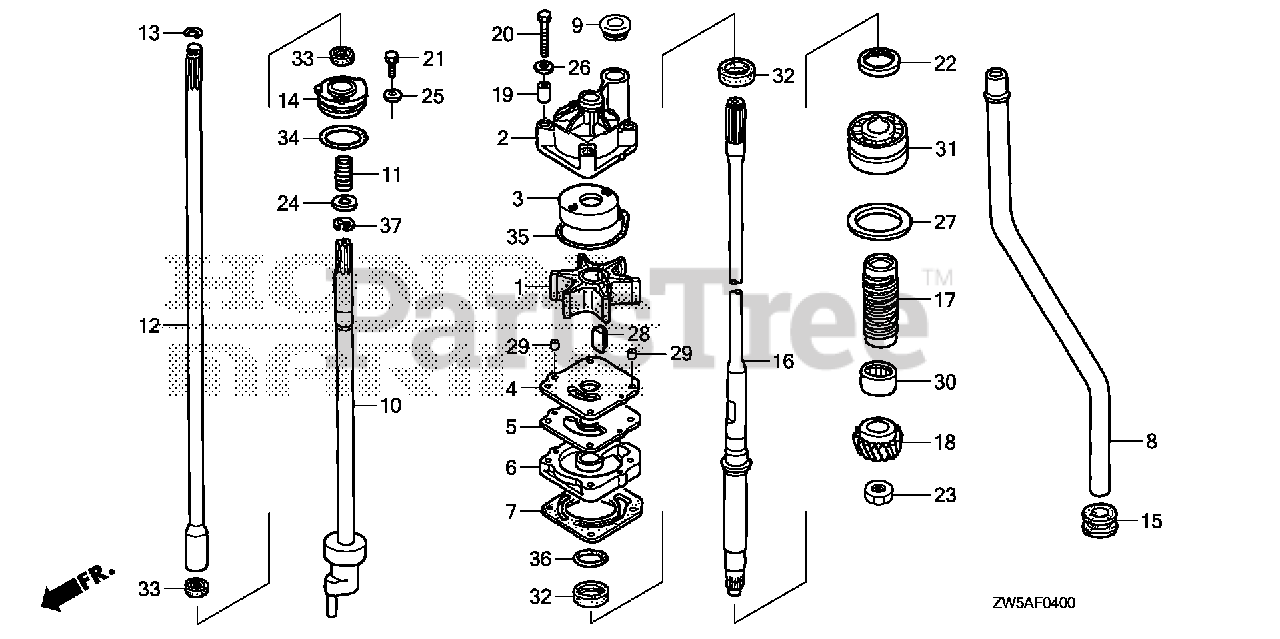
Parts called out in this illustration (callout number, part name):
1	IMPELLER, PUMP
2	HOUSING, IMPELLER
3	LINER, PUMP
4	COVER, IMPELLER
5	GASKET B, IMPELLER
6	HOUSING, WATER PUMP
7	GASKET, WATER PUMP
8	TUBE, WATER (UL)
9	RING, WATER TUBE SEAL
10	ROD, SHIFT (UL)
11	SPRING, SHIFT ROD
12	ROD A, SHIFT (L)
13	RING, STOPPER
14	HOLDER, SHIFT ROD
15	GROMMET, EXTENSION CASE
16	SHAFT, VERTICAL
17	SLINGER, OIL
18	GEAR, PINION
19	COLLAR, DISTANCE
20	BOLT, HEX. (8X55)
21	BOLT, HEX. (6X12)
22	NUT, LOCK (64MM)
23	NUT, HEX. (18MM)
24	WASHER, PLAIN (12MM)
25	WASHER, PLAIN (6MM)
26	WASHER (8MM)
27	SHIM A, GEAR (0.10)
27	SHIM B, GEAR (0.15)
27	SHIM C, GEAR (0.30)
27	SHIM D, GEAR (0.50)
28	KEY, WOODRUFF
29	PIN, DOWEL (6X10)
30	BEARING, NEEDLE (1-1/2X1-1/4)
31	BEARING, TAPER ROLLER (30X62X40)
32	SEAL, WATER (23X36X6)
33	SEAL, WATER (12X21X6)
35	O-RING, WATER PUMP
36	O-RING (58.5X3.5)
37	E-RING (10MM)
